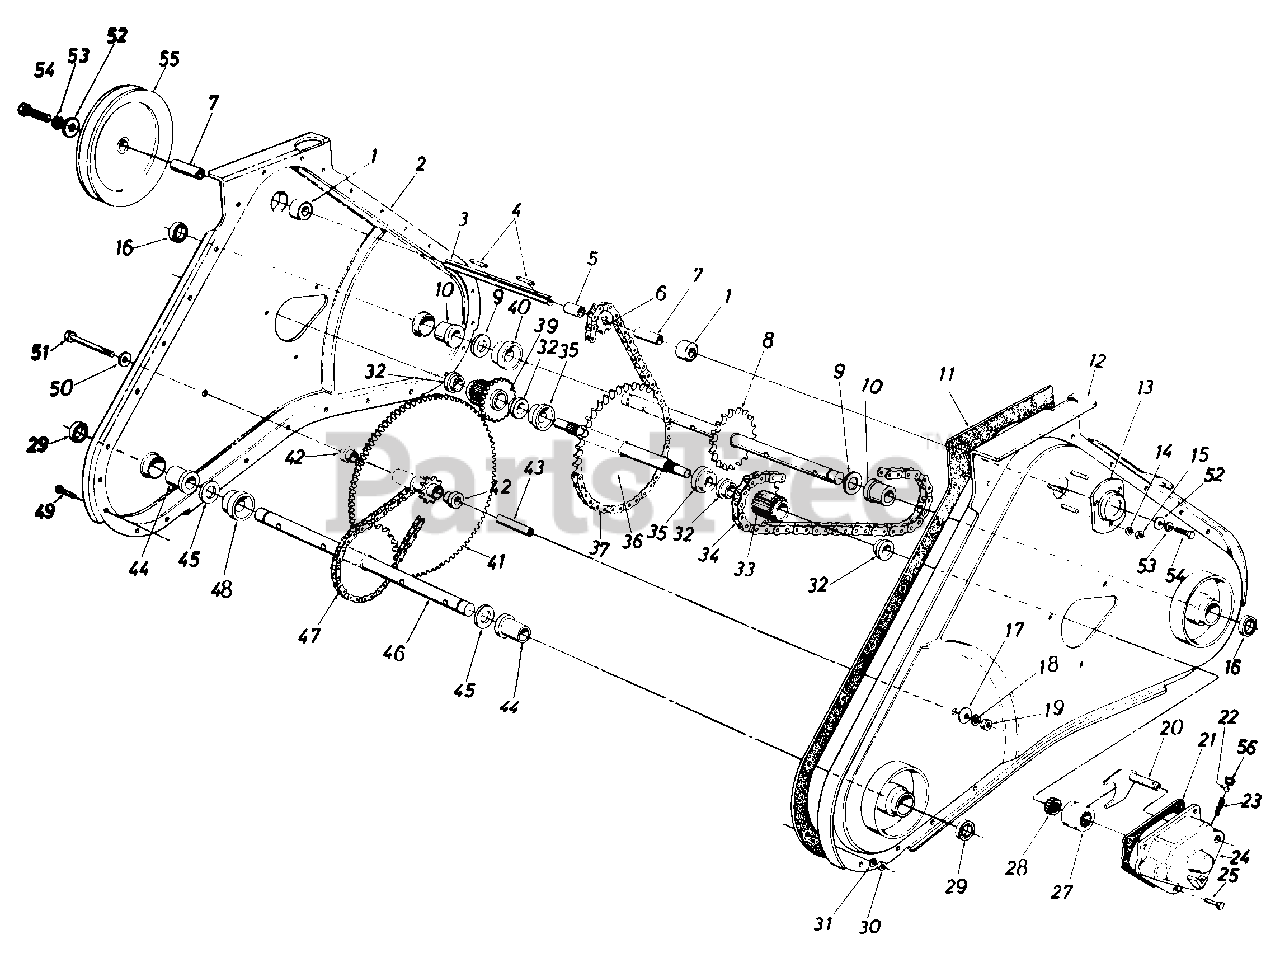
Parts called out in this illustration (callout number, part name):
1	Ball Bearing .62" I.D. x 1.38" O.D. x .44
2	Chain Case R.H. Half
3	Input Shaft .62" Dia.
4	Sq. Key 3/16" x 3/16" x .75" Lg.
5	Spacer .637" I.D. x .781" O.D. x .85" Lg.
6	Sprocket 9 Tooth x .62" Shaft
7	Spacer .637" I.D. x .781" O.D. x 1.44" Lg.
8	Tine Shaft Ass'y.
9	Fl-Wash. 1.0" I.D. x 1.62" O.D.
10	Flange Bearing 1.0" I.D.
11	Gasket - Housing
12	Chain Case L.H. Half
13	Bearing Housing 1-3/8" O.D.
14	L-Wash. 1/4" I.D.
15	Hex Nut 1/4-28 Thd.
16	Seal 1.0" I.D. x 1.38" O.D.
17	Belleville Wash.
18	L-Wash. 3/8" I.D.
19	Hex Cent. L-Nut 3/8-24 Thd.
20	Shift Yoke Ass'y. - L.H.
21	Gasket - Shift Housing
22	Ball Detent .250 Dia.
23	Compression Spring
24	Shift Housing - L.H.
25	Hex Self-Tap Scr. 5/16-18 x .75" Lg.
27	Clutch Dog
28	Clutch Dog Driver
29	Seal 1.0" x 1.38" O.D.
30	Hex Nut 1/4-28 Thd.
31	L-Wash. 1/4" I.D.
32	Flange Brg. 1.00" I.D.
33	Sprocket Brg. Sleeve Ass'y.
34	#50 Chain - 5/8" Pitch x 50 Links - Endless
35	Stepped Spacer 1.0" I.D. x 1.75" O.D.
36	Clutch Shaft Ass'y.
37	#420 Chain 1/2" Pitch x 58 Links - Endless
39	Gear Bearing - Sleeve Ass'y.
40	Spacer 1.0" I.D. x 2.0" O.D. x .68" Lg.
41	Sprocket and Gear Ass'y.
42	Flange Brg. .628" I.D. x .753" O.D.
43	Hub Sleeve .38" I.D. x .625" O.D.
44	Flange Brg. 1.00" I.D. x 1.188" O.D.
45	Fl-Wash. 1.0" I.D. x 1.62" O.D.
46	Axle Shaft Ass'y.
47	#420 Chain 1/2" Pitch 46 Links - Endless
48	Spacer 1.0" I.D. x 2.0" O.D.
49	Hex Bolt 1/4-28 x .62" Lg.
50	Belleville Wash.
51	Hex Bolt 3/8-24 x 2.75" Lg.
52	Fl-Wash. 5/16" I.D.
53	L-Wash. 5/16" I.D.
54	Hex L-Bolt 5/16-24 x .75" Lg.
55	Input Pulley - Chain Case
56	Cap Plug .250" Dia.
